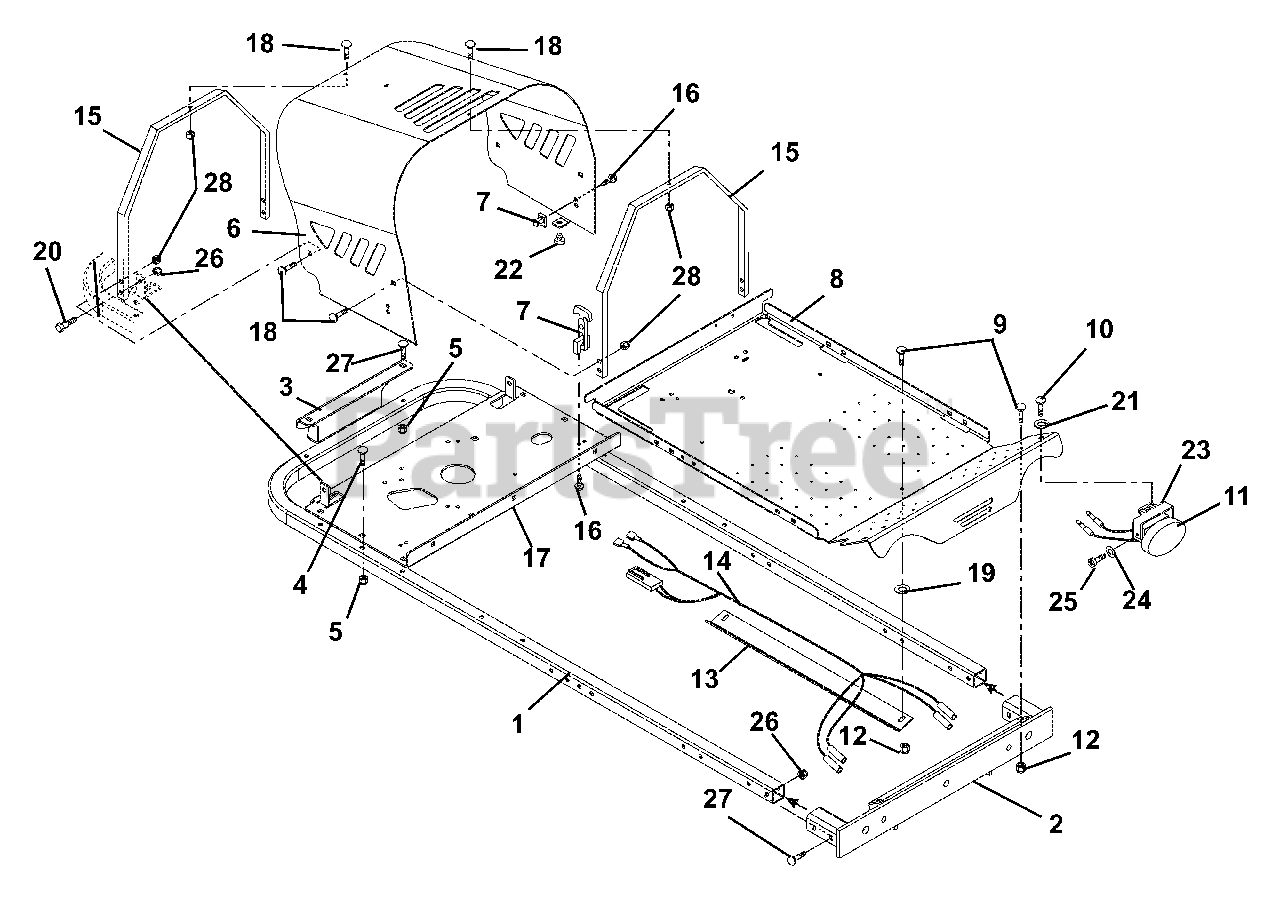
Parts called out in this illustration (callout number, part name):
1	Tube, Frame
2	Weldment, Axle Mount
3	Trailer Hitch with Decal
4	Bolt, Round Head Square Neck .38-16 x 2.5 Grade 5
5	Nut .38-16 Flange Nyloc
6	Hood, Zoom
7	Latch, Rubber
8	Footrest
9	Bolt, Round Head Square Neck .31-18 x 1.00 Grade 5
10	Screw-Cap Button Head .31-18 x .50 Grade 5
11	Assembly, Light
12	Nut .312-18 Flange Nyloc
13	Bracket, Harness
14	Harness, Light
15	Brace, Hood
16	Screw-Machine 10-24 x .50 Hex Washer Head
17	Plate, Engine
18	Bolt, Round Head Square Neck .31-18 x .62
19	Washer, Flat Steel .38 x .87 x .179
20	Bolt, Shoulder .375-16 x .135
21	Washer, Locking .31 x .078 Regular
22	Button Bumper
23	Bracket, Light
24	Washer, Locking 4MM x 1MM Regular Cone Lock
25	Screw, Socket Head Cap M4 x .07 x 8
26	Nut-Locking-Top-Flange .38-16
27	Bolt-Round Head Square Neck .38-16 x 2.25 Grade 5
28	Nut-Locking-Top-Flange .31-18
